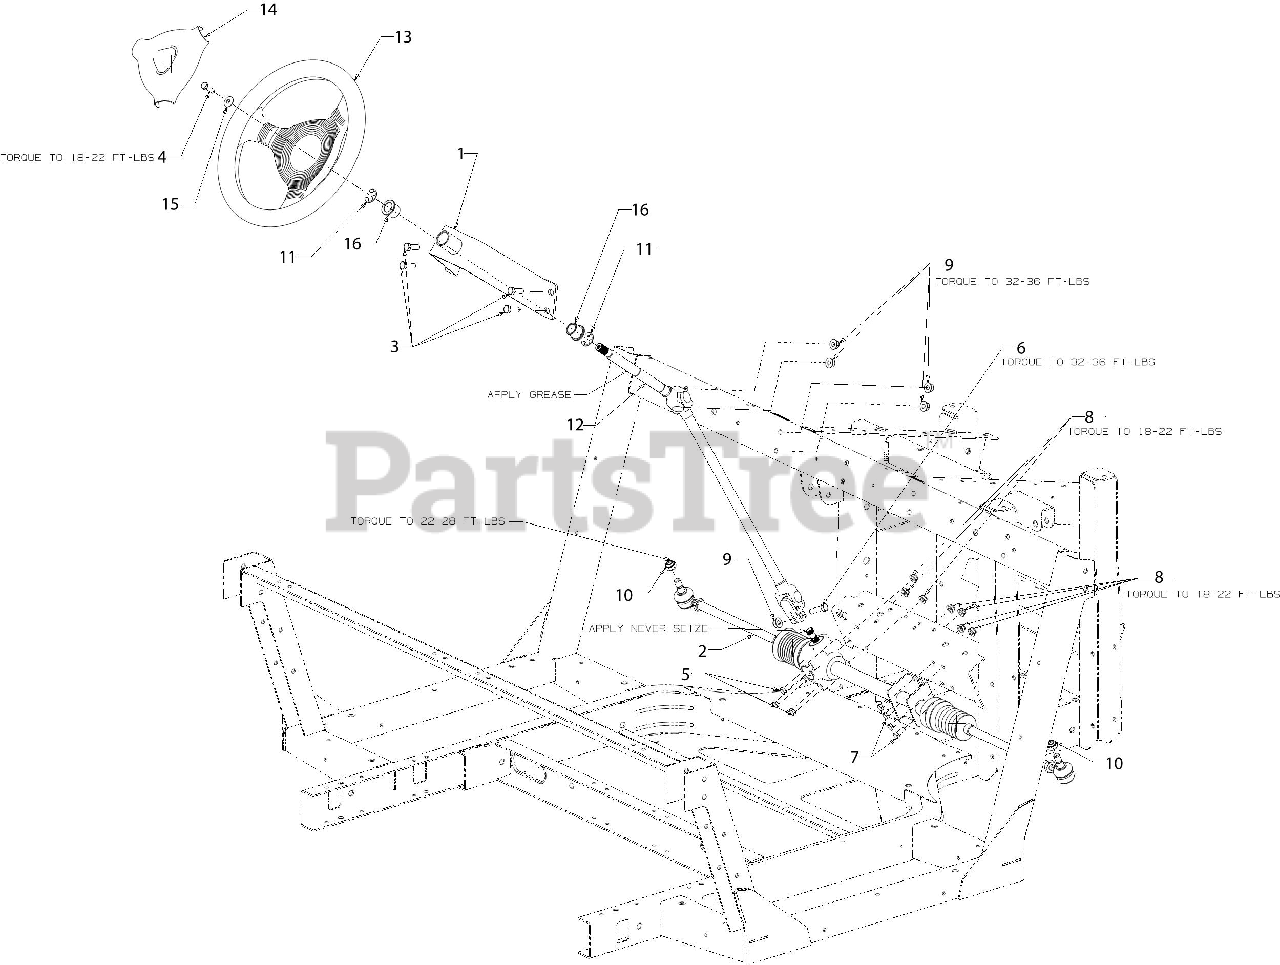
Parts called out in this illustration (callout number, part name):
1	STEERING WHEEL SUPPORT ASSEMBLY
2	STEERING ASSEMBLY
3	SCREW 3/8-16 x 1 GR5
4	SCREW 5/16-18 x 1.00 GR5
5	SCREW 5/16-18X3.5 GR5
6	SCREW 3/8-16 x 1.25 GR5
7	SCREW 5/16-18 x .75 GR5
8	FLANGE LOCK NUT 5/16-18
11	E-RING
12	STEERING SHAFT
13	STEERING WHEEL 3-SPOKE
14	STEERING WHEEL COVER
15	BELL WASHER .337 X.867 x .057
16	FLANGE BEARING
